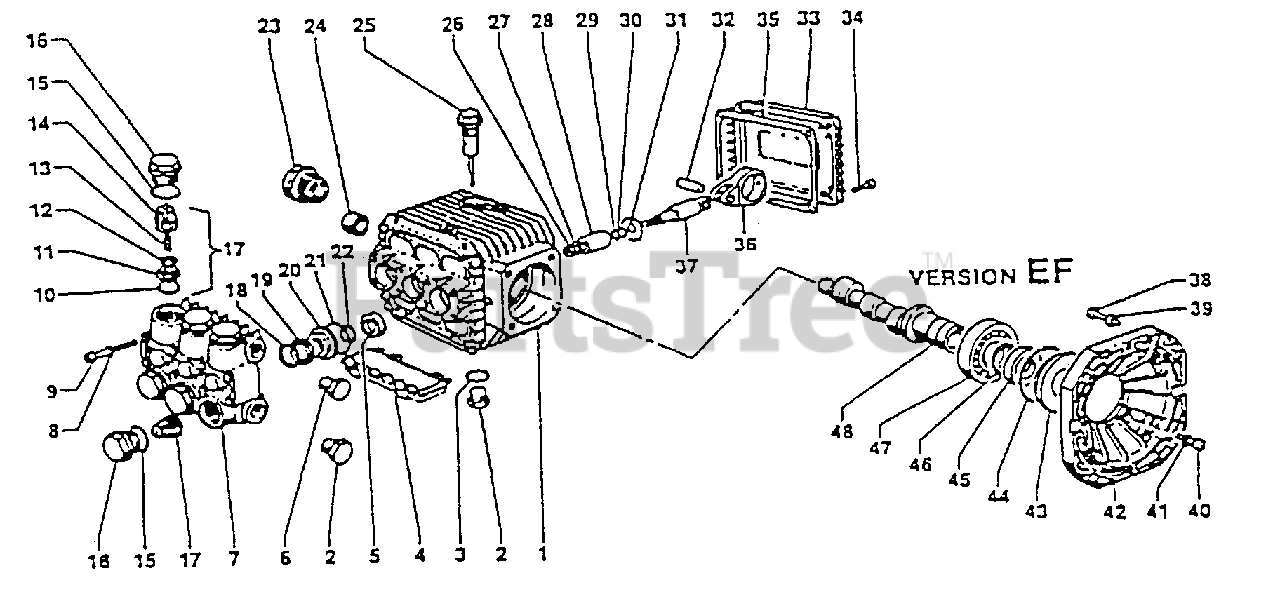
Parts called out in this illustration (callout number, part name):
7	Manifold, Alum.
12	Valve Plate
17	Valve Assy.
20	Packing Retainer
23	Sight Gauge
24	Needle Bearing
25	Oil Dip Stick
28	Piston (15 mm)
30	Back Up Ring
31	Flinger Washer
32	Connecting Rod Pin
33	Crankcase Cover
35	Cover Gasket
36	Connecting Rod End
37	Piston Guide
38	Screw
39	Washer
40	Screw
41	Washer
42	Flange
43	Spacer
44	O-Ring
45	Oil Seal
46	Snap Ring
47	Bearing
48	Crankshaft
